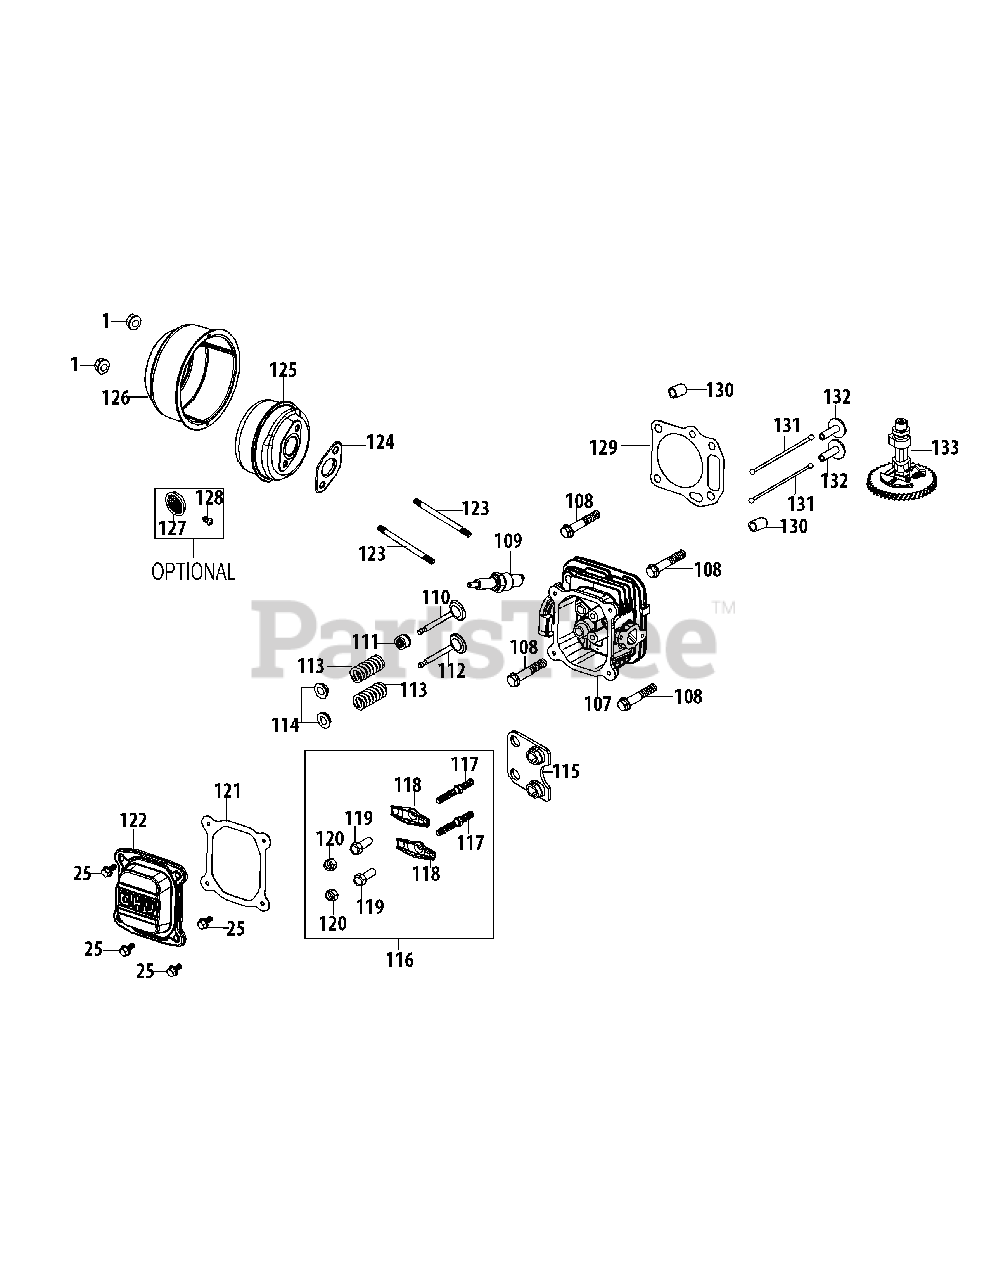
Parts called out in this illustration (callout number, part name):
1	Nut M6X10Mm Starter/Carb/Muff
25.1	Bolt M6X14 Multi-Purpose
107	Cylinder Head Assembly
107.1	Cylinder Head
108	Bolt M8X54 Cylinder Head
109	Spark Plug/F5Rtc
110	Intake Valve
111	Intake Valve Seal
112	Exhaust Valve
113	Valve Spring
114	Valve Spring Retainer
115	Push Rod Guide
116	Rocker Arm Assembly
117	Rocker Arm Stud
118	Rocker Arm
119	Fulcrum Nut
120	Jam Nut
121	Valve Cover Gasket
122	Valve Cover
123	Muffler Stud M6X76
124	Muffler Gasket
125	Muffler Assembly
126	Muffler Shield
127	Spark Arrestor
128	Spark Arrestor Screw
129	Cylinder Head Gasket
130	Cylinder Head Dowel Pin 10×16
131	Push Rod
132	Tappet
133	Camshaft Assembly
